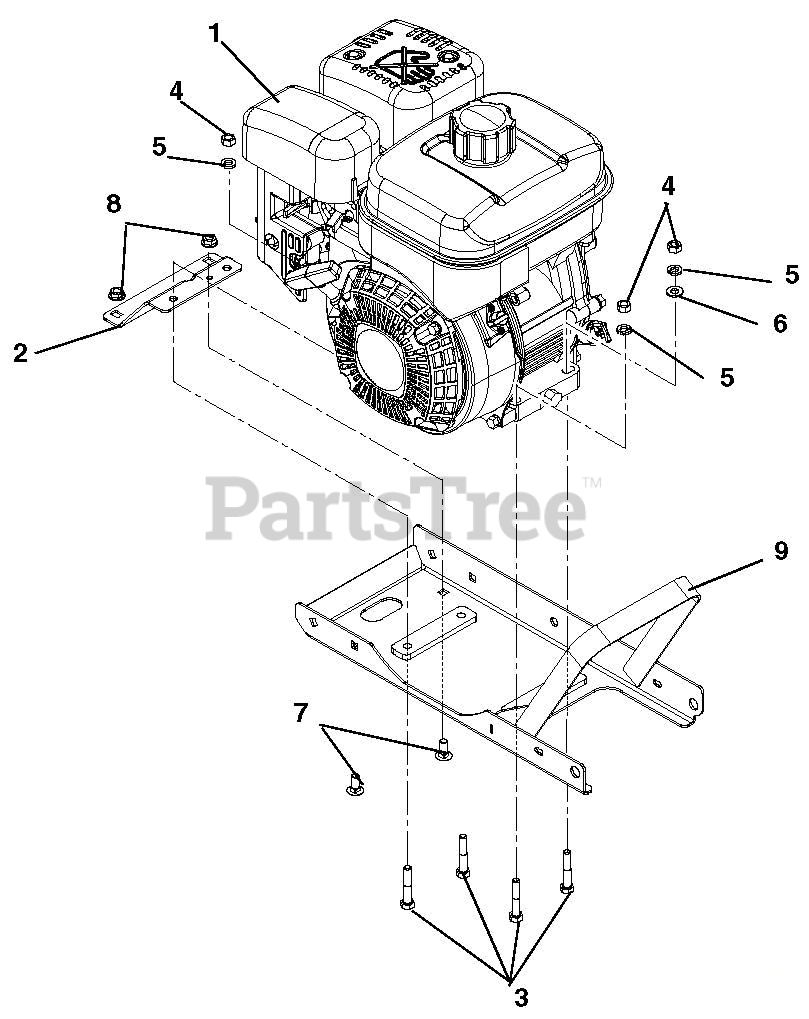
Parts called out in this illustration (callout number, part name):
1	ENGINE,SUBARU 6HP SP170 (CARB)
2	BRACKET, REINFORCEMENT
3	@BLT-HEX .31-18X1.75 GR5 YWZC
4	@NUT-HEX .31-18 YWZC
5	WSHR-LK .312X.097 HVY YWZC
6	@WSHR-FL-STL.344X.688X.065YWZC
7	@BLT-RDHDSQNK .31-18X.75 G5YZ
8	@NUT-LK-TOP-FLG .31-18 YWZC
9	FRAME,EDGER
